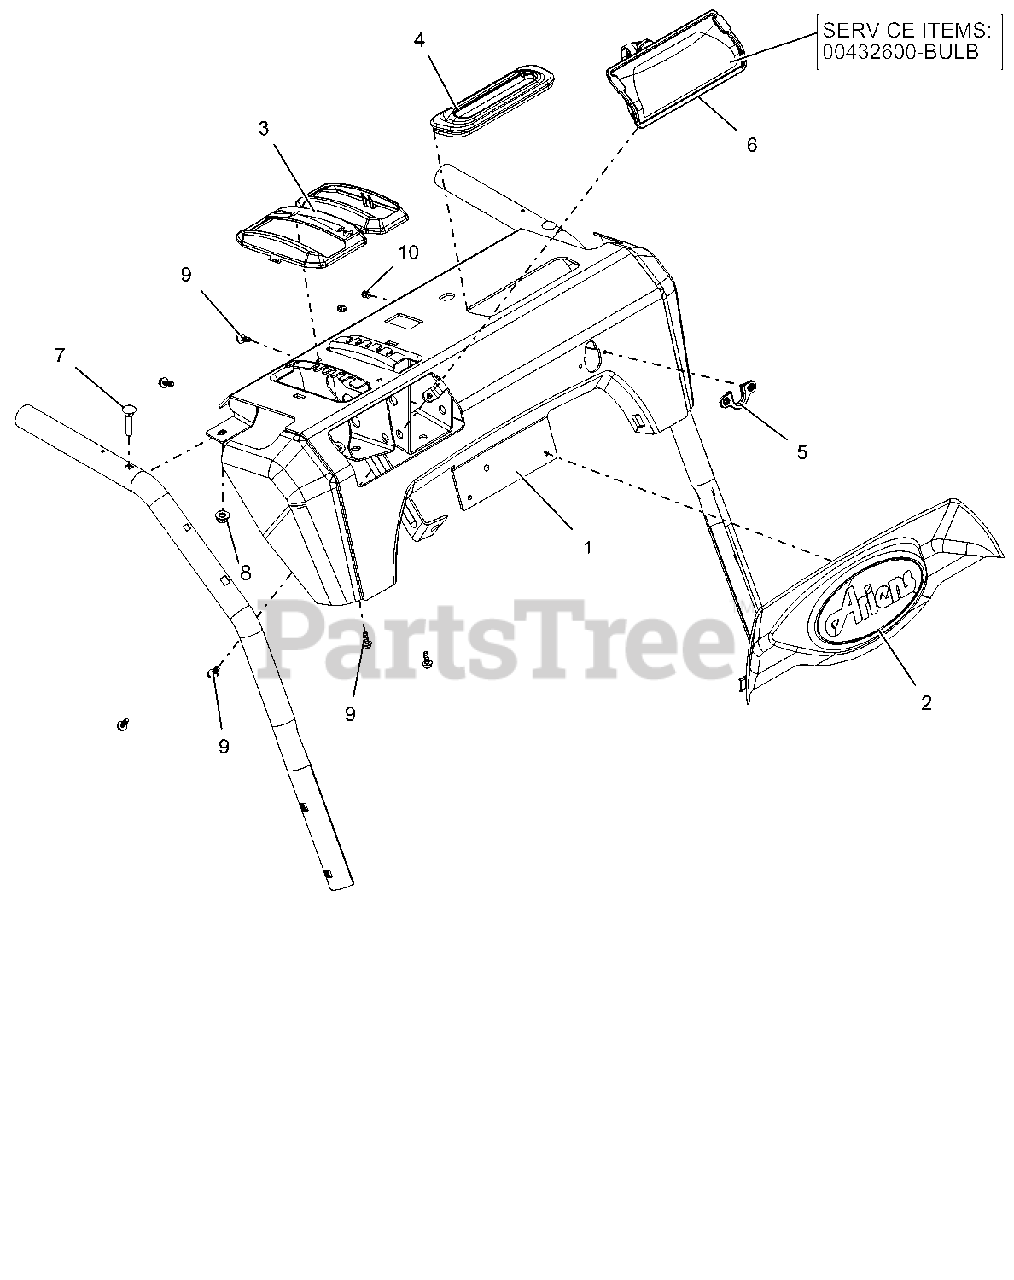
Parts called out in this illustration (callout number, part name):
1	WELDMENT,DASH-LG FRICTION QT
2	BEZEL, DASH-ARIENS LG DASH
3	BEZEL, SHIFT - FRICTION SNOW
4	GROMMET, BOOT, QUICK TURN
5	GROMMET, CABLE, QUICK TURN 2
6	HEADLIGHT ASY, HALO 20W 2SHOT
7	BLT-RDHDXLSQNK.25-20X1.25 G5ZC
8	@NUT-LK-CTR-FLG .25-20 YWZC
9	SCR-TAP #10X.50 BOSS INDHXHD
10	RVT-POP #43 .125X.313 STL ZINC
11	BULB, LIGHT-HALOGEN 20W
